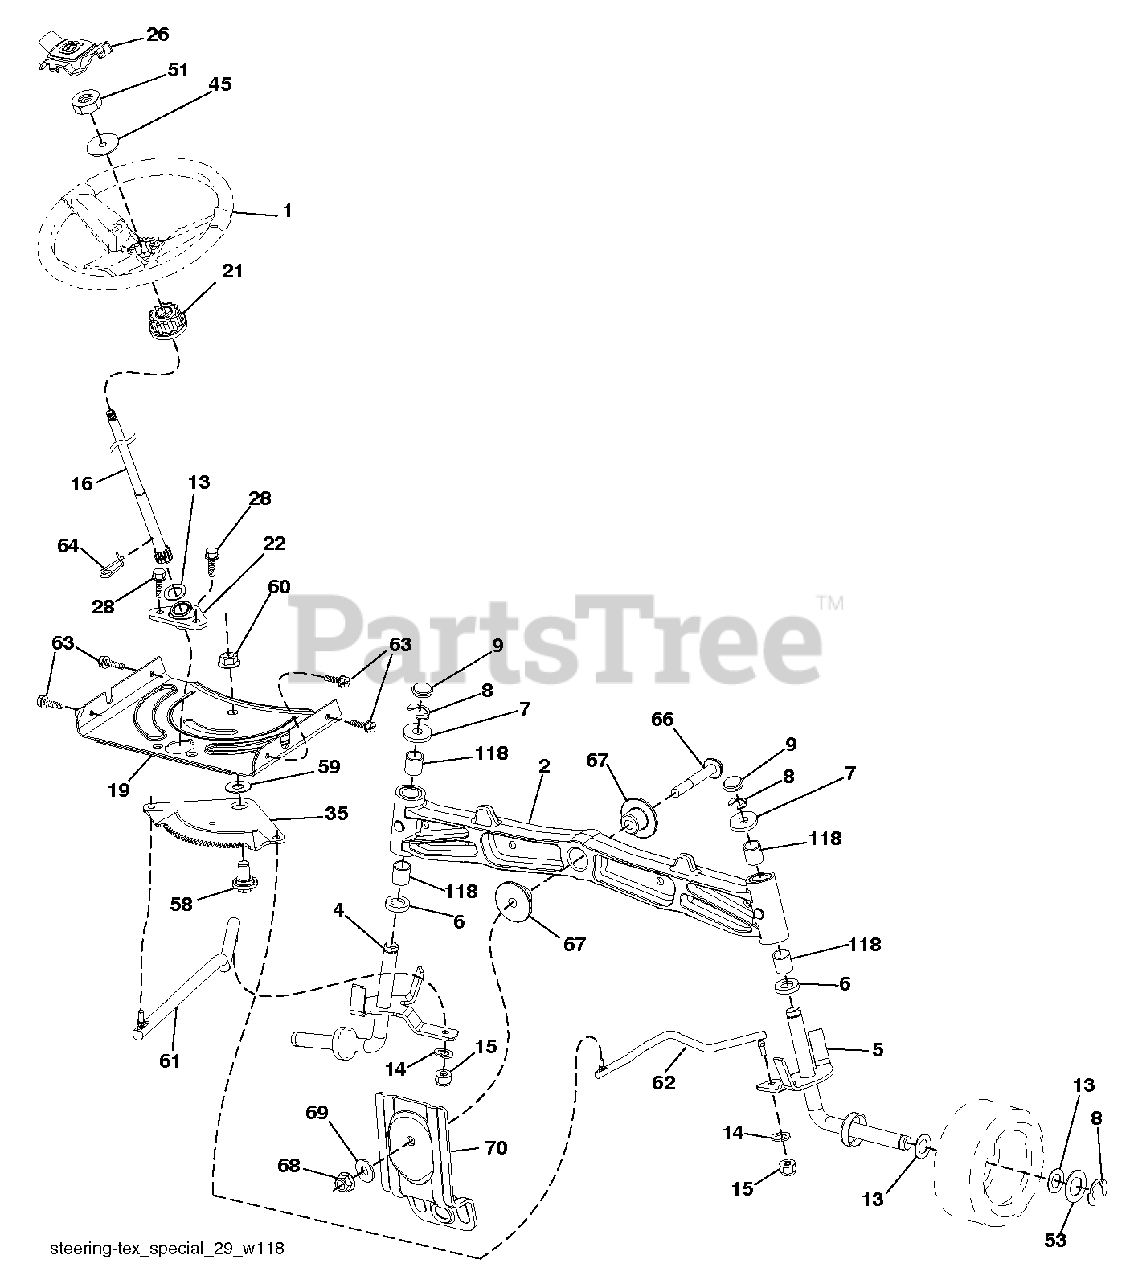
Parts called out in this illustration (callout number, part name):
1	WHEEL.STEER.HUSQ.SR.498.OVMLD
2	AXLE.CAST.IRON
4	SPINDLE.ASM.LH.16"TIRE.CE
5	SPINDLE.ASM.RH.16"TIRE.CE
6	THRUST WASHER
9	CAP.SPINDLE.BLACK
14	WASHER, LOCK 3/8
15	NUT CROWNLOCK 3/8-24
16	SHAFT.STEER.STEALTH.DD
19	PLATE.STEER.DDL.NLT/NG
21	ADAPTER, WHEEL STNG..
22	STEERING.SUPT.LOWER.
26	INSERT.CAP.WHL.STRG.HUSQ.PREM
28	SCREW, 3/8-16X3/4
35	GEAR.SECTOR.PLATE.DDL.
45	WASHER 9/16"ID, 2 3/8"OD
51	NUT.HEX.1/2-20
53	WASHER.HARDENED
58	BOLT.SHOULDER.SECTOR.P
59	WASHER.THURST.SECTOR.S
60	NUT FLANGE LOCK 5/8-11
61	DRAGLINK.LH.BALLSTUD.D
62	DRAGLINK.RH.BALLSTUD.D
63	SCREW
64	RETAINER.CLIP.SPRING.S
66	BOLT HEX FGHD 7/16-14 X 3 SERR
67	BUSHING.PM.FRONT AXLE
68	NUT.LOCK.FLANGE.7/16
69	WASHER.1.5X.505X.118
70	BRKT.DECK.SUSPENSION.F
118	BUSHING, AXLE CAST
